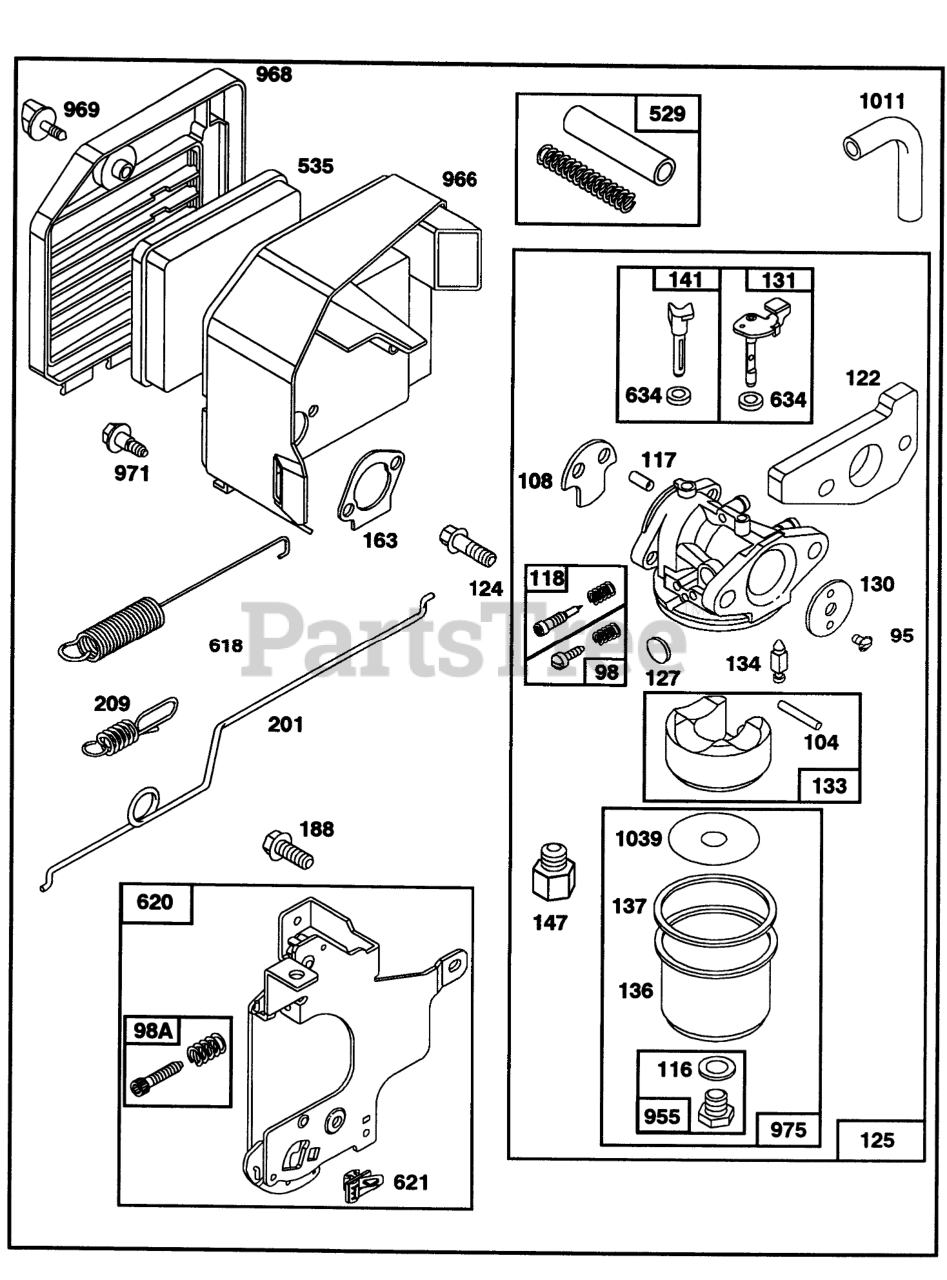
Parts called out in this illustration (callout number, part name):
95	SCREW - ROUND HEAD
98	IDLE ADJUSTING SCREW
98A	SPEED ADJUST. SCREW ASM
104	FLOAT HINGE PIN
108	CHOKE VALVE
116	SEALING GASKET
117	JET
118	VALVE KIT - NEEDLE
122	ADAPTER ASSEMBLY
124	HEX HEAD SCREW
125	CARBURETOR ASSEMBLY
127	PLUG
130	THROTTLE VALVE
131	THROTTLE SHAFT
133	FLOAT-CARBURETOR
134	Valve-Float (Includes Seat)
136	FLOAT BOWL
137	FLOAT BOWL GASKET
141	CHOKE SHAFT
147	JET ADAPTER
163	AIR CLEANER GASKET
188	SCREW - SEM
201	GOVERNOR LINK
209	GOVERNOR SPRING
529	BREATHER TUBE
535	FILTER ELEMENT
618	RETURN SPRING
620	CARBURETOR BRACKET
621	STOP SWITCH
634	SEAL WASHER
955	HEX HEAD SCREW
966	AIR CLEANER BASE
968	AIR CLEANER COVER
969	AIR CLEANER SCREW
971	AIR CLEANER SCREW
975	CARBURETOR BOWL ASM
1011	VENT TUBE
1039	FLOAT LIMITER
